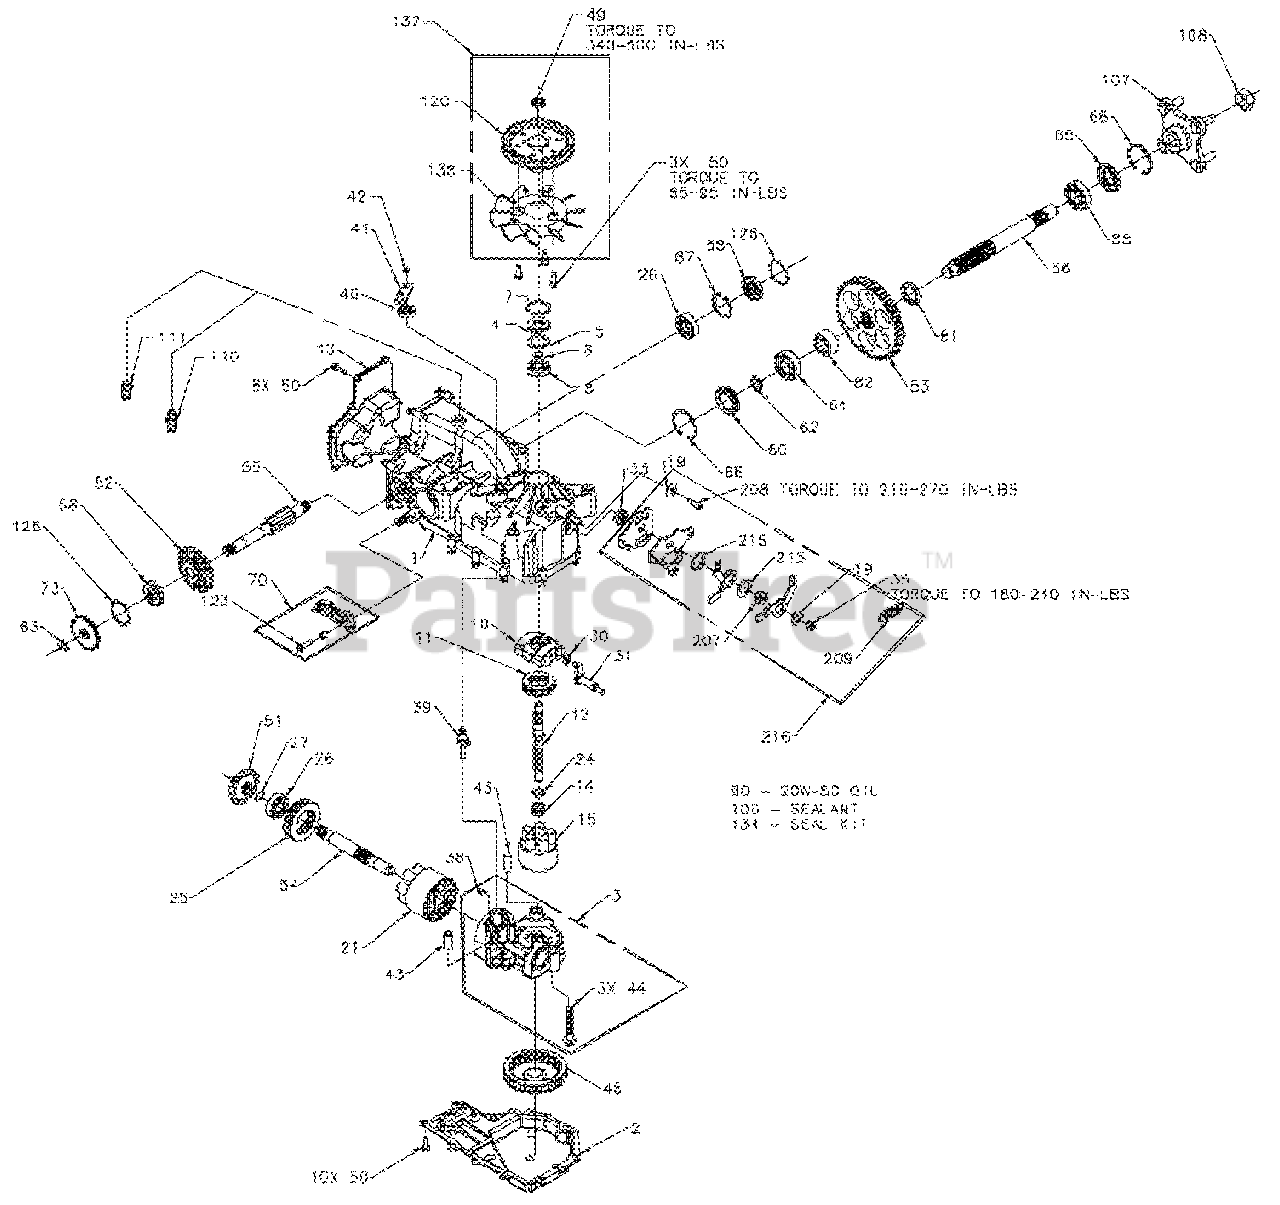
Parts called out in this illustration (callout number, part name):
1	Kit, Housing - Main
3	Kit, Center Section
4	Lip Seal
5	Spacer
6	Wire Retaining Ring
7	Retaining Ring
8	Ball Bearing
10	Variable Swashplate
11	Thrust Bearing .30 x .52 x .13
12	Input Shaft
13	Cover, Back
14	Spring, Block
18	10 cc Cylinder Block
19	Washer
21	21 cc Cylinder Block Assembly
24	Washer, Block Thrust
25	Thrust Bearing .42 x .68 x .15
26	Ball Bearing
27	Wire Retaining Ring
30	Slot Guide
31	Trunnion Arm
33	Lip Seal
35	Nut
38	Kit, Bypass Plate
39	Bypass Actuator
40	Lip Seal
41	Bypass Arm
42	Retaining Ring
43	Pin
44	Screw
46	Filter
49	Nut, Hex Lock .50-20 with Nylon Insert
50	Screw, .25-20 with Nylon Insert
51	14 Teeth Bevel Gear
52	19 Teeth Bevel Gear
53	53 Teeth Spur Gear
54	Motor Shaft
55	Brake Shaft
56	Axle Shaft
57	Seal, Lip 17 x 40 x 70
60	Seal Plug - Side
62	Retaining Ring - Axle
63	Retaining Ring Kit
64	Bearing - Ball 20 x 47 x 14 (6204)
65	Bearing - Ball 25 x 47 x 12 (6005)
66	Seal
67	Retaining Ring
68	Retaining Ring - Axle
70	Brake Arm Service Assembly - Left Hand
73	Brake Disc
80	20W - 50 Oil
81	Axle Bushing
82	Axle Bushing
100	Sealant
107	Hub Assembly
108	Nut, Hex .75-16
110	Fitting, O-Ring Assembly
111	Cap Vent Assembly
120	Kit, Seal
123	Screw, Hex Washer Head .25-20 x .875
126	Retaining Ring
134	Kit, Seal
137	Kit, Fan /Pulley
207	Spacer, RTN
208	Screw, .938-24 x .75 (Patch)
209	Spring, Extension
215	Washer, Nylon
216	Kit, RTN
